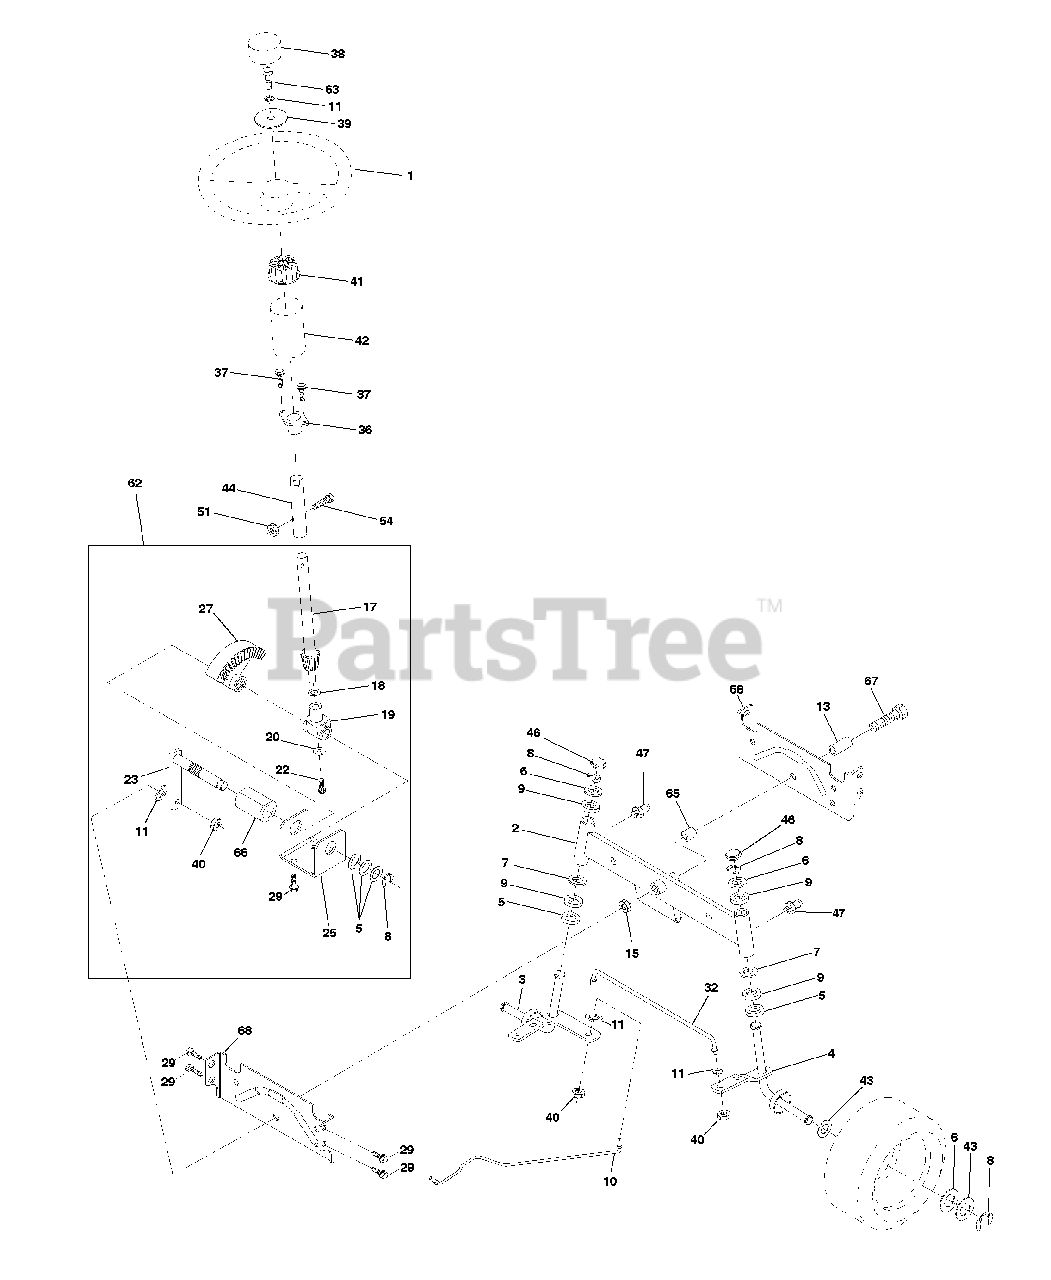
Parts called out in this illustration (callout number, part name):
1	Wheel Steering
2	Axle Front Casting Machined
3	Spindle Asm LH
4	Spindle Asm RH
5	Bearing Race Thrust Harden
6	Washer 25/32 X 1-5/8 X 16 Ga
7	Washer 27/32 X 1-1/4 X 16 Ga
8	Ring Klip #t5304-75
9	Bearing Col Strg Blk
10	Link Drag Extended Cast
11	Washer Lock Hvy Hlcl Spr 3/8
13	Bearing Axle STLT/GT
15	Nut Lock Flange 5/8-11 Unc
17	Shaft Asm Strg
18	Washer Thrust 515 x 750 x 033
19	Support Shaft
20	Washer Shim 1/4 X 5/8 X 062
22	Screw Cap Sckt Hd Phos & Oil
23	Shaft Asm Pittman
25	Bracket Steering
27	Gear Sector
28	Washer 13/32 X 7/8 X 16 Ga
29	Screw Thdrol 3/8-16x3/4 Ty-tt
32	Rod Asm Tie Ball
36	Bushing Strg
38	Insert Cap Strg Wh Au
39	Washer 13/32 X 2-3/8 X 8 Ga
40	Lock nut
41	Adaptor Wheel Strg
42	Boot Steering Shaft
43	Washer 25/32 X 1 1/4 X 16 Ga
44	Extension Steering Shaft LR/LT
46	Cap Spindle Fr Top Blk
47	Fitting Grease
51	Nut Lock Hex w/Ins 5/16-18
54	Bolt Fin Hex 5/16-18 Unc x 1-1/4
62	Kit, Steering Assembly Svc
63	Bolt Fin Hex 3/8-16unc x 1 Gr. 5
65	Spacer Axle
66	Bearing Arm Pittman
67	Bolt, Fin Hex 5/8-11 UNC x 2-3/4
68	Axle, Brace
